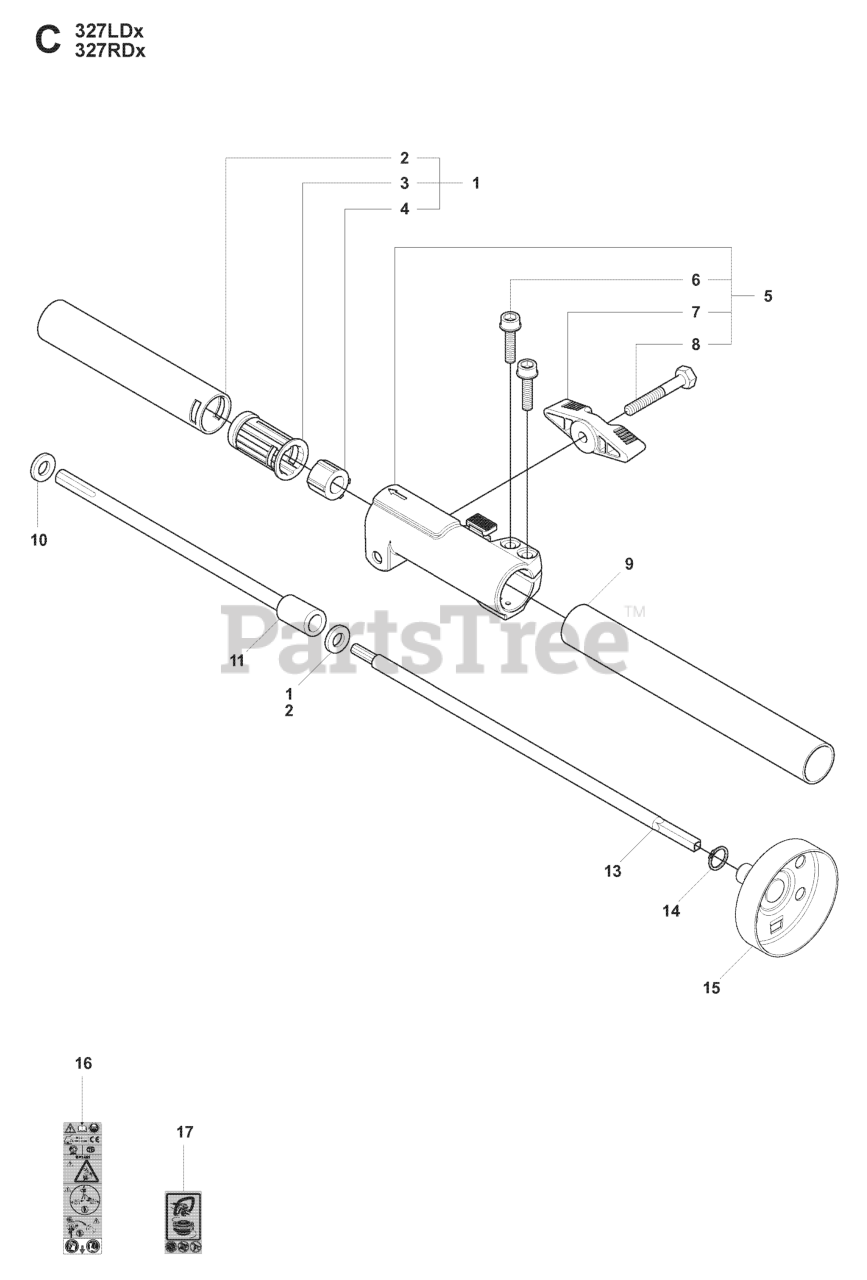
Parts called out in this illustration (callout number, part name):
1	%TUBE ASSY COMPLETE
3	PLUG
4	BUSHING
5	CLAMPING SLEEVE
6	SCREW
11	SHAFT LOWER
14	RETAINING RING SGA 10
15	CLUTCH DRUM
16	RP WARNING DECAL
17	DECAL WARNING "NO BLADES"
